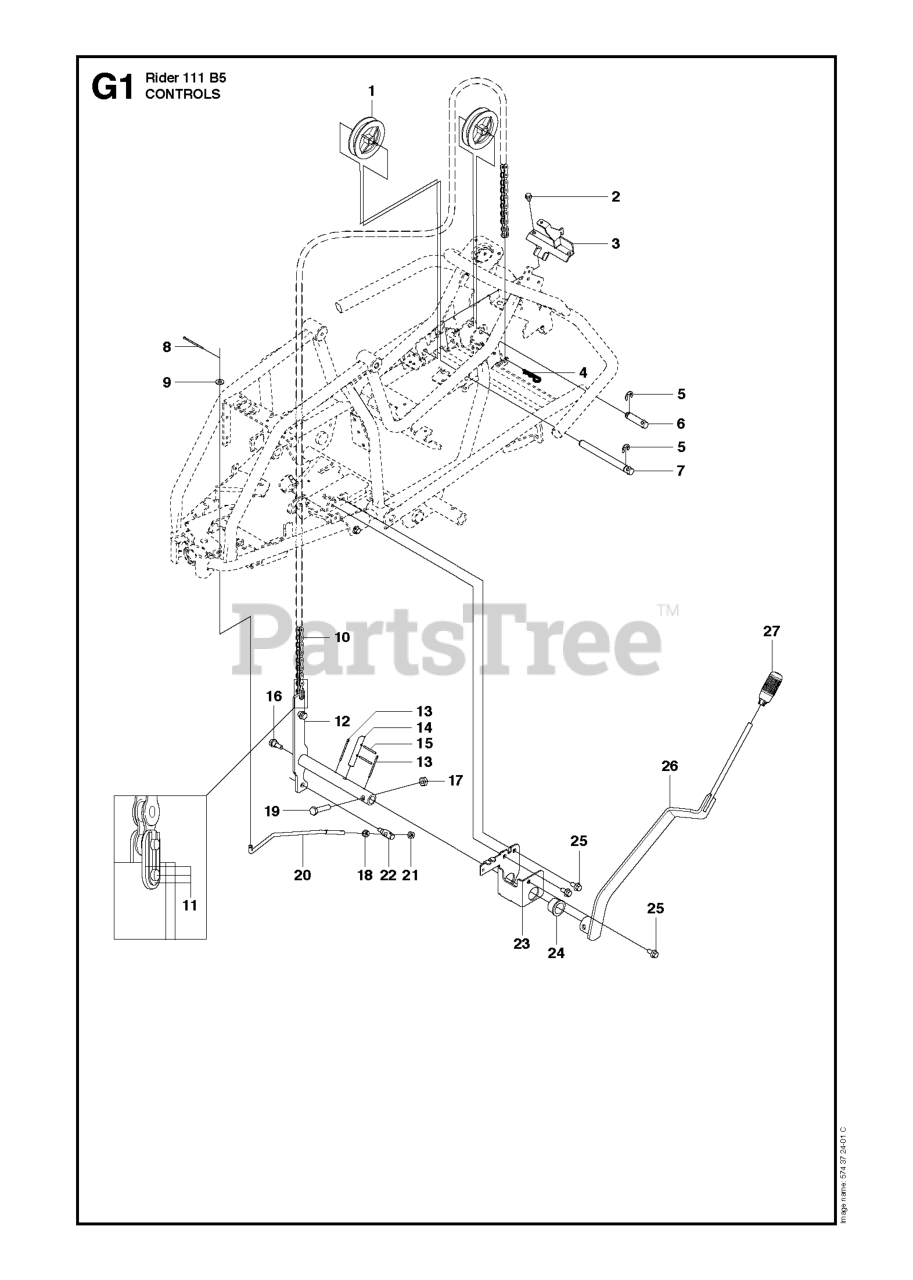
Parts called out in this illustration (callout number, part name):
9	WASHER BRB 8.4X17
13	COTTER PIN
14	RP PIN
17	NUT
18	NUT
19	REPL BY 725 25 00-71
21	LOCKNUT M8
23	BRACKET ASSY
24	BEARING FLANGE
27	GEAR STICK KNOB
